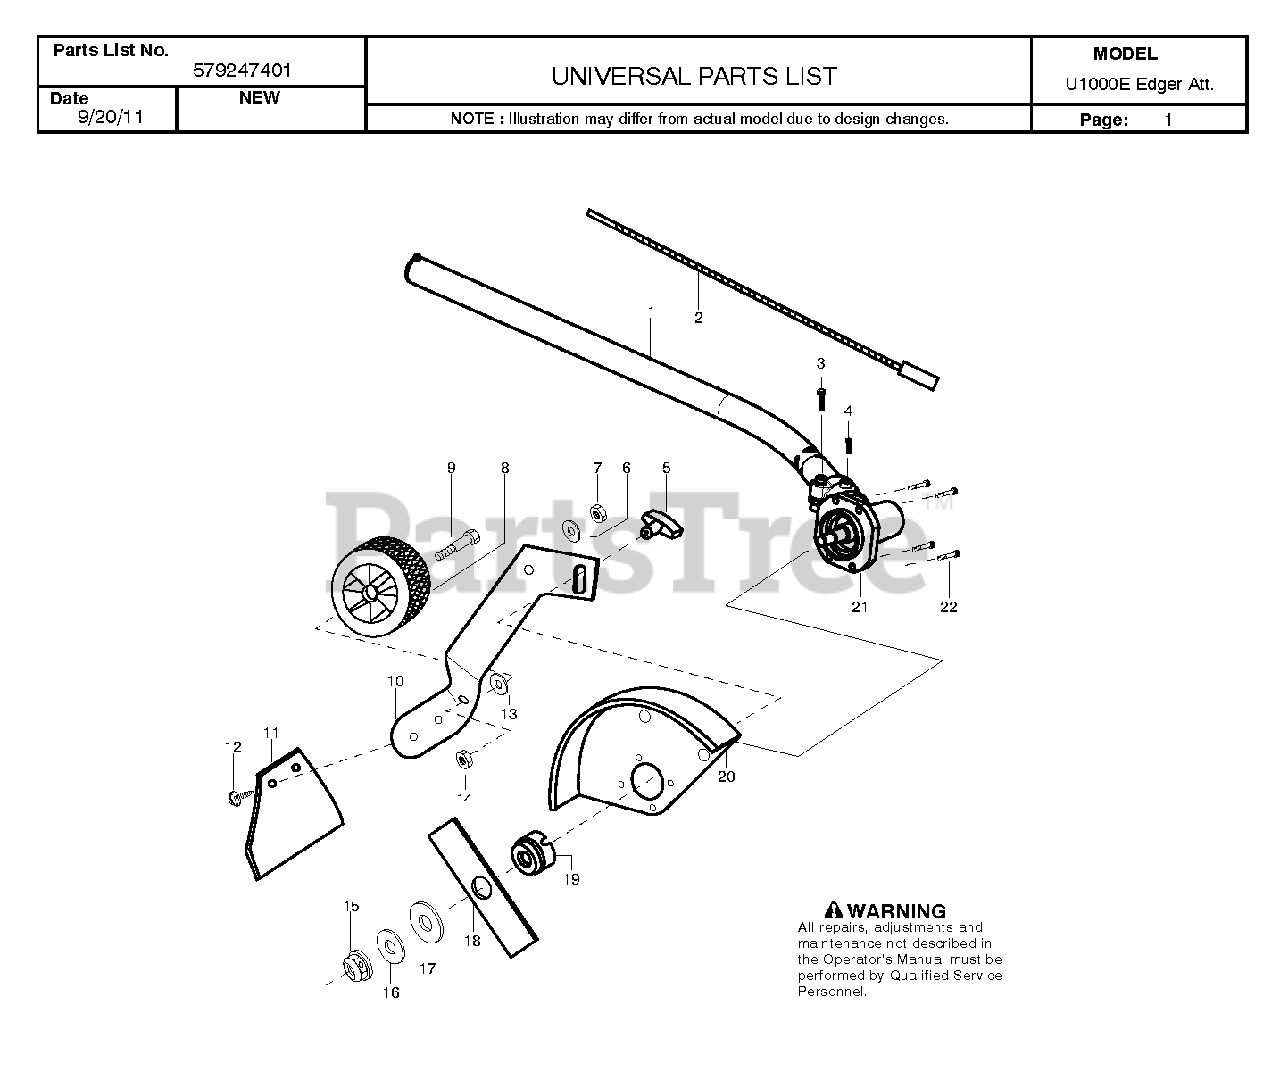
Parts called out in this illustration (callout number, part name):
1	DRIVE SHAFT KIT ASSY
2	FLEXSHAFT
3	SCREW - CARB. ADAPTOR
4	SCREW 8-16 X 9/16 (PLAS
8	WHEEL-4"(FRONT)(RUBBER)
9	BOLT-SHOULDER AXLE
10	WHEEL BRKT ADJ
11	KIT MUD FLAP
12	FASTENER MUD FLAP
15	NUT-FLANGE (LH)
16	WASHER BELLVILLE
17	WASHER-FLAT.
19	DUST CUP
20	KIT,EDGER GUARD
21	GEARBOX
22	SCR 10-24 MS LDK PAN PH
